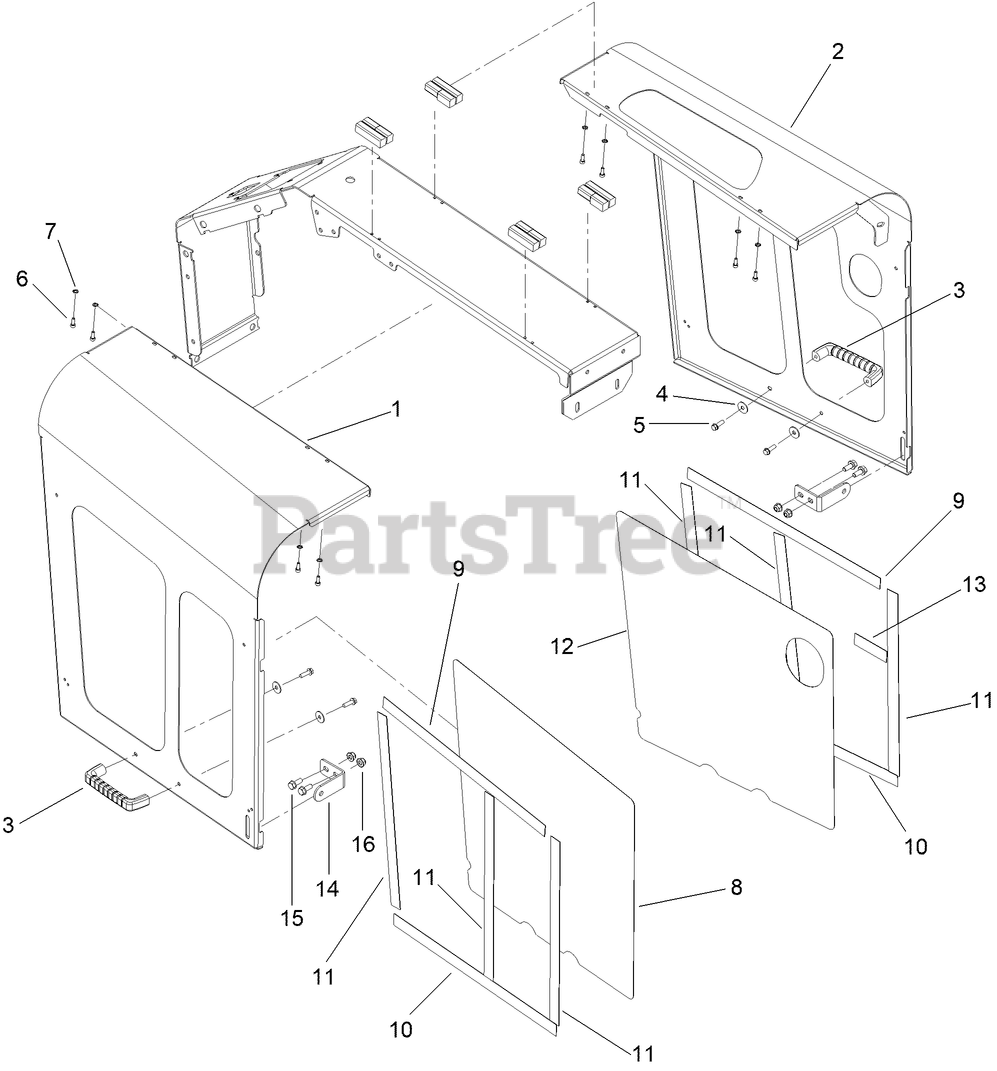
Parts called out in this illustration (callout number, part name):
1	HOOD-LOCKING, RH
2	HOOD-LOCKING, LH
3	HANDLE-DOOR
4	WASHER-PLAIN
5	SCREW-HWH
6	SCREW -HSH
7	WASHER-LOCK, EXT
8	SCREEN-RIGHT SIDE
9	VHB TAPE (1.0") HIGH ENERGY
10	VHB TAPE (1.0") HIGH ENERGY
11	VHB TAPE (1.0") HIGH ENERGY
12	LEFT DOOR SCREEN
13	VHB TAPE (1.0") HIGH ENERGY
14	BRACKET-LOCK
15	SCREW-HHF
16	NUT-HF, NI
